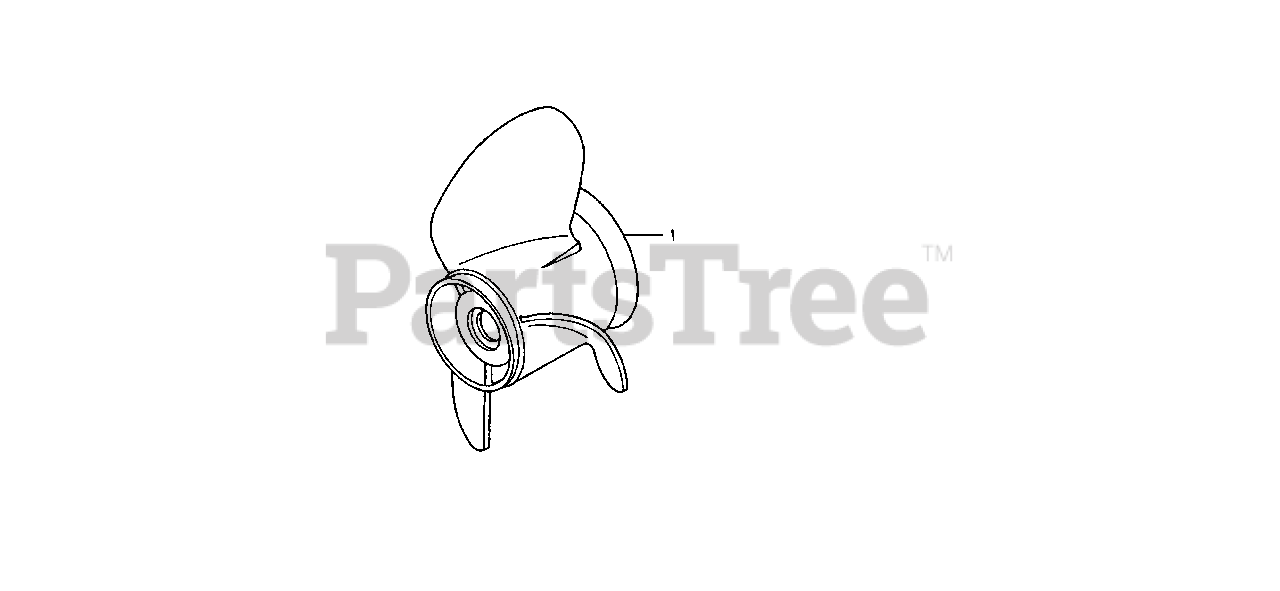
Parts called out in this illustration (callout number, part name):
1	PROPELLER, THREE-BLADE (13-1/4X15)
1	PROPELLER, THREE-BLADE (13-1/4X17)
1	PROPELLER, THREE-BLADE (13-1/4X19)
1	PROPELLER, THREE-BLADE (13-1/4X21)
